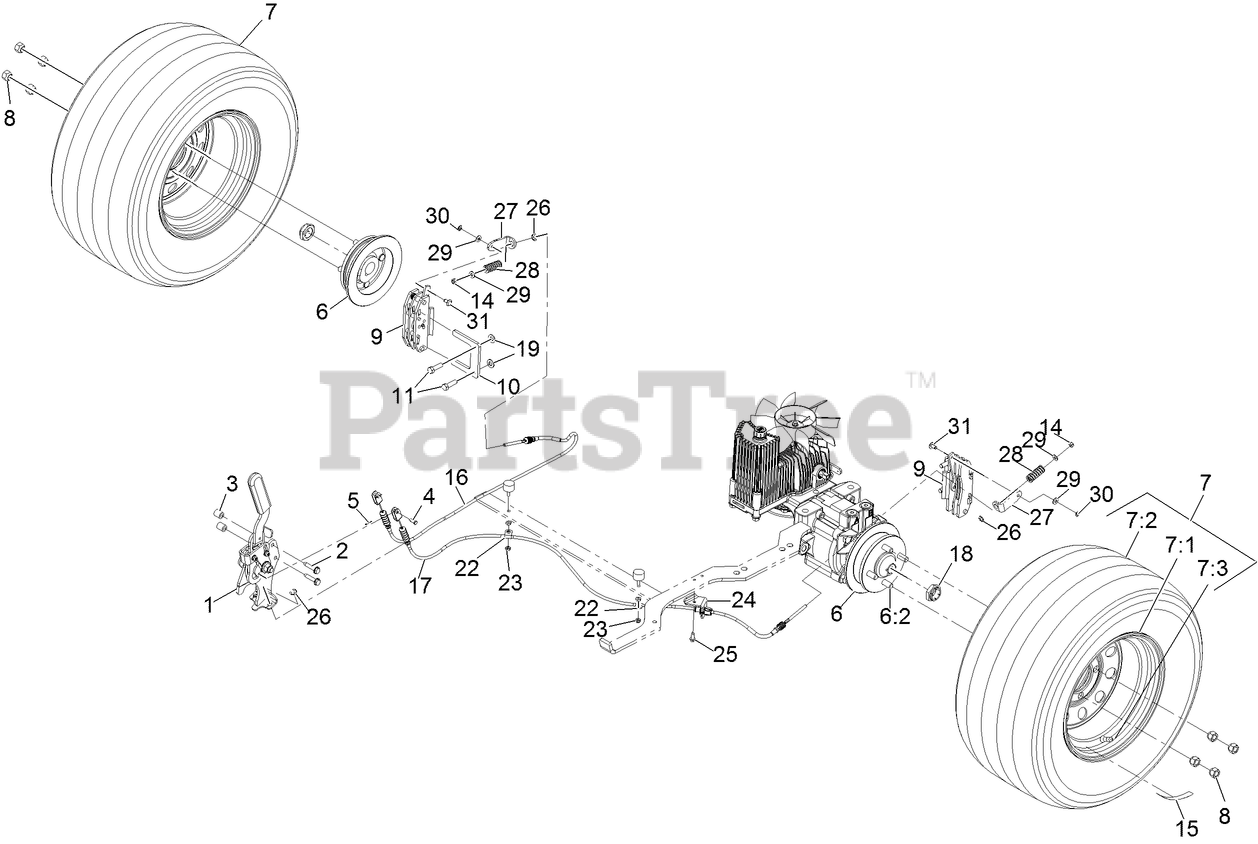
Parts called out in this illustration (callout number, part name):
1	BRAKE HANDLE ASM
3	SPACER
4	PIN-CLEVIS
5	PIN-COTTER
6	WHEEL HUB ASM
6:2	STUD-WHEEL
7	WHEEL AND TIRE ASM
7:3	STEM-VALVE
8	NUT-LUG
9	CALIPER-BRAKE
10	PLATE-MOUNT, BRAKE
11	SCREW-LOCK, PATCH
14	NUT-LOCK, NI
15	DECAL-WHEEL NUT TORQUE
16	CABLE-PARK BRAKE, RH
17	CABLE-PARK BRAKE, LH
18	LOCKNUT
19	WASHER-FLAT
23	NUT-LOCK, NI
24	BRACKET-CABLE
25	SCREW-HWH
26	E-RING
27	BRACKET-BRAKE, L
28	SPRING-DIE
29	WASHER-FLAT
30	E-RING
31	PIN-BRAKE
